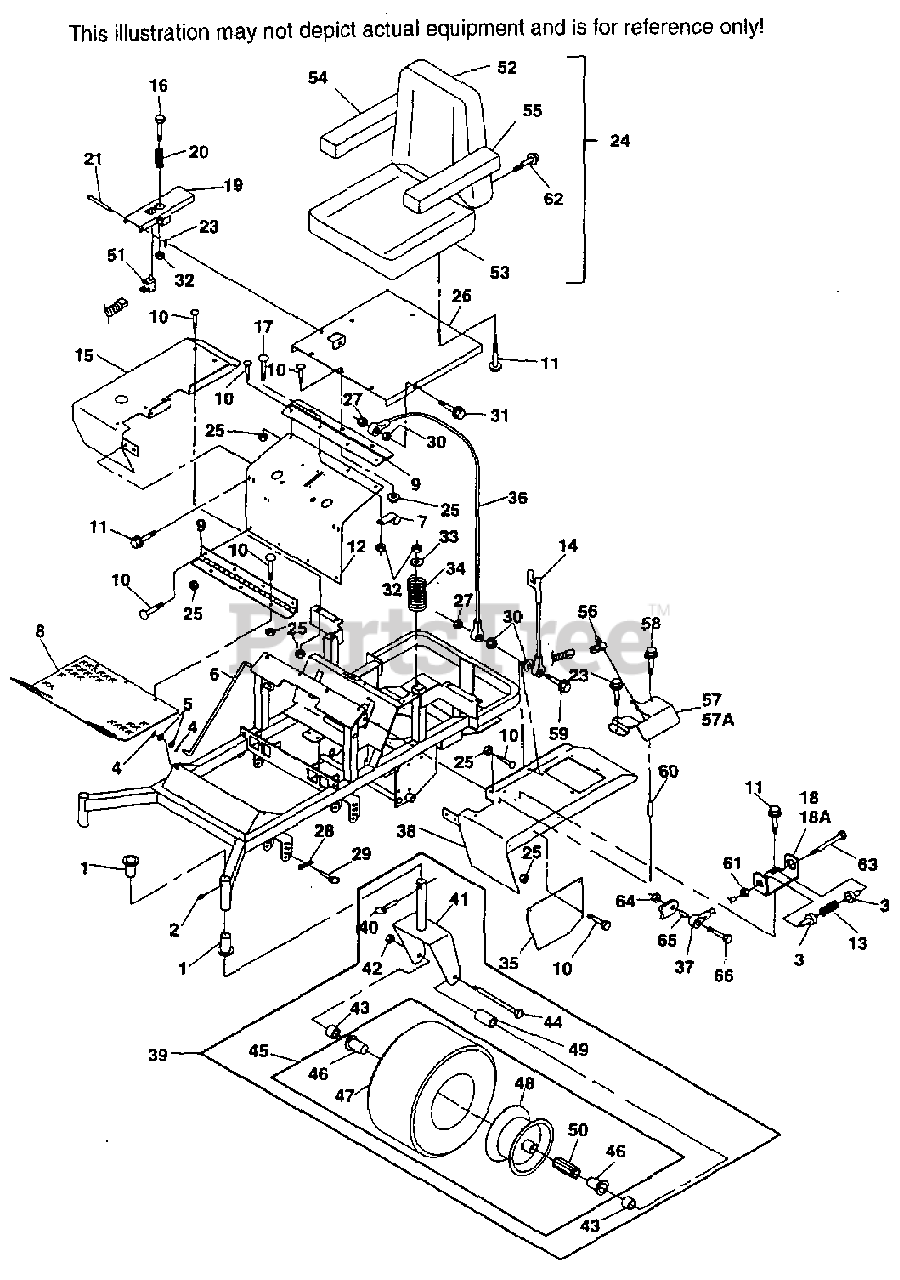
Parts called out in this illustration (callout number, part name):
1	BUSHING
2	GREASE FITTING
3	BUSHING, SPRING KEEPER
4	HAIR PIN, .08" DIAMETER
5	FLATWASHER, 3/8" SPECIAL
6	ROD, FOOT PLATE LATCH
8	FOOT PLATE
9	HINGE
11	CAP SCREW, 5/16-18 X 3/4" SERRATED
12	KICK PLATE
13	NEUTRAL RETURN SPRING
14	CABLE, SEAT STOP
15	FENDER ASSEMBLY, RH(WITH DECAL)
18	RETAINER, NEUTRAL SPRING, LH
18A	RETAINER, NEUTRAL SPRING, RH
19	SEAT SWITCH BRACKET
20	SPRING
21	CLEVIS PIN
23	HAIR PIN COTTER
24	SEAT ASSEMBLY
25	NUT, 5/16-18 SERRATED FLANGE HEX HEAD
26	SEAT BASE
27	HEX NUT, 1/4-20 ELASTIC STOP
28	HAIR PIN
29	RING PIN
30	NUT, 1/4-20 SERRATED FLANGE HEX HEAD
31	CAP SCREW, 1/4-20 X 1" SERRATED
32	ELASTIC STOP NUT, 5/16-18
34	SEAT SPRING
35	FENDER PANEL, LH
36	CABLE, SEAT STOP
37	BALL JOINT, NEUTRAL
38	FENDER - LH
39	CASTER WHEEL YOKE ASSEMBLY, COMPLETE
40	QUICK PIN
41	CASTER WHEEL YOKE
43	SPACER
45	WHEEL ASSEMBLY, COMPLETE
46	RETAINER
47	TIRE ONLY
48	RIM ONLY
49	SLEEVE
50	ROLLER BEARING
51	SEAT SWITCH
52	SEAT BACK CUSHION
53	SEAT BOTTOM CUSHION ASSEMBLY
54	ARM PAD, RH
55	ARM PAD, LH
56	NEUTRAL INTERLOCK SWITCH
57	NEUTRAL LOCK BRACKET, RH
57A	NEUTRAL LOCK BRACKET, LH
58	CAP SCREW, 5/16-18 X 2-3/4" SERRATED
59	CAP SCREW, 1/4-20 X 1-1/2" SERRATED
60	SPACER, NEUTRAL LOCK BRACKET
61	HEX NUT, 3/8-24 UNF
62	HEX HEAD SCREW W/WASHER, 1/4-20 X 3/4"
63	HEX HEAD BOLT, 3/8-24 X 6-1/2", UNF
65	SPACER NEUTRAL SPRING
